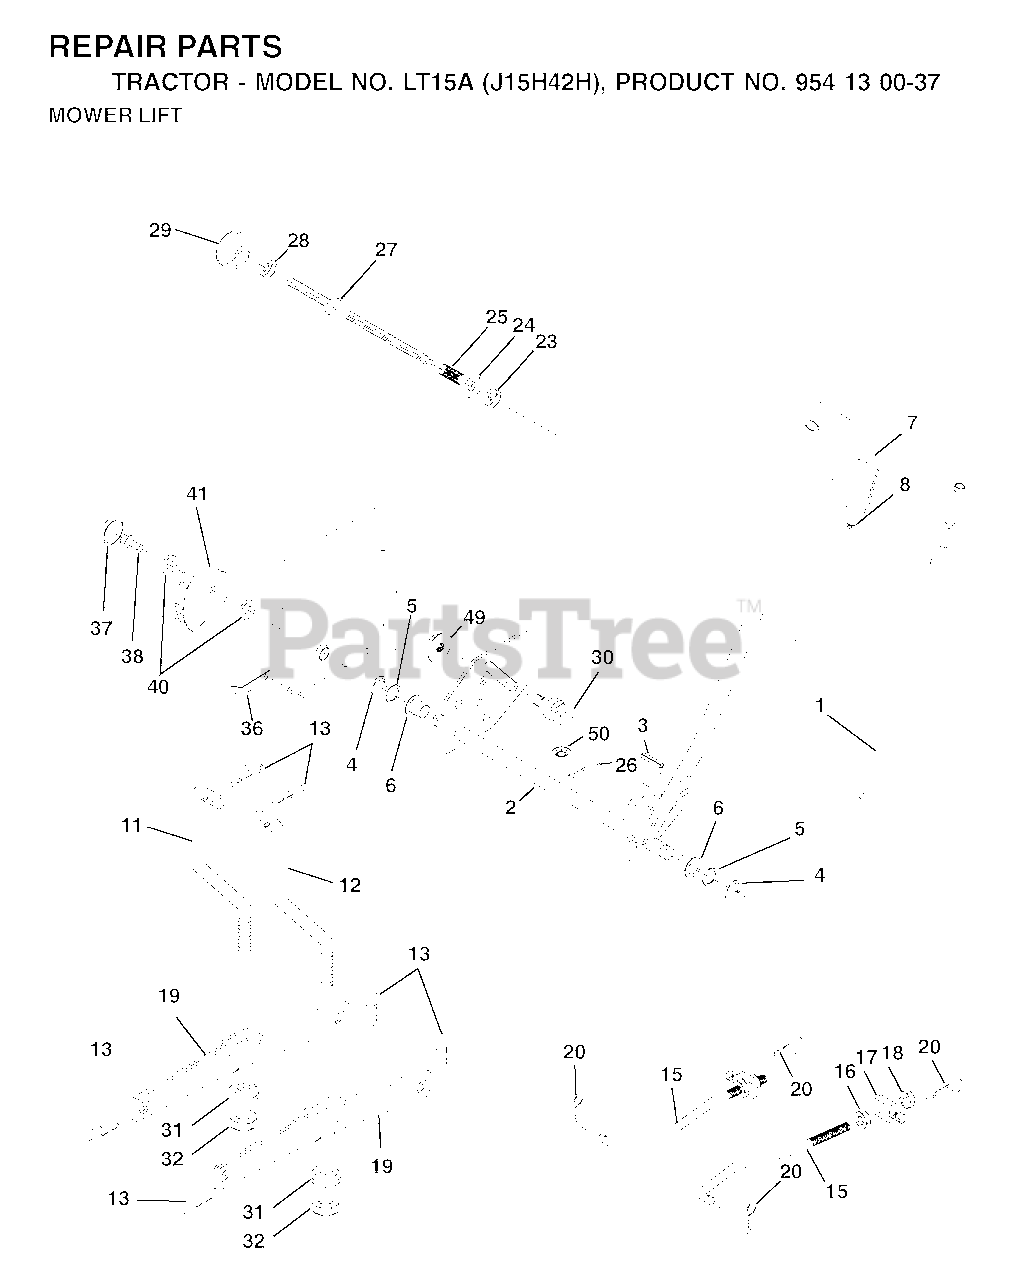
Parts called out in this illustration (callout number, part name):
1	WIRE ASM INNER W/ PLUNGER LT
2	SHAFT ASM R HANDLE
3	PIN GROOVE
4	RETAINING RING LT
6	BEARING.NYLON
7	GRIP HANDLE
11	LINK LIFT LH
12	LINK LIFT RH
13	RETAINER-SPRNG RB
15	LINK.SUSPENSION.FRONT
16	NUT
17	TRUNION
18	NUT
19	ARM.REAR.SUSPENSION
20	SPRING RETAINER
25	SPRING**
26	RETAINER CLIP
27	ROD ADJ LIFT
28	NUT
29	KNOB INF 3/8-16
31	BEARING.PIVOT.LIFT
32	NUT CROWNLOCK 3/8-24
36	POINTER, HEIGHT INDICATOR
37	PLUG,HOLE
38	SCREW 5/16-18X1
41	IND. HEIGHT STLT
49	NUT
50	NUT PUSH M
